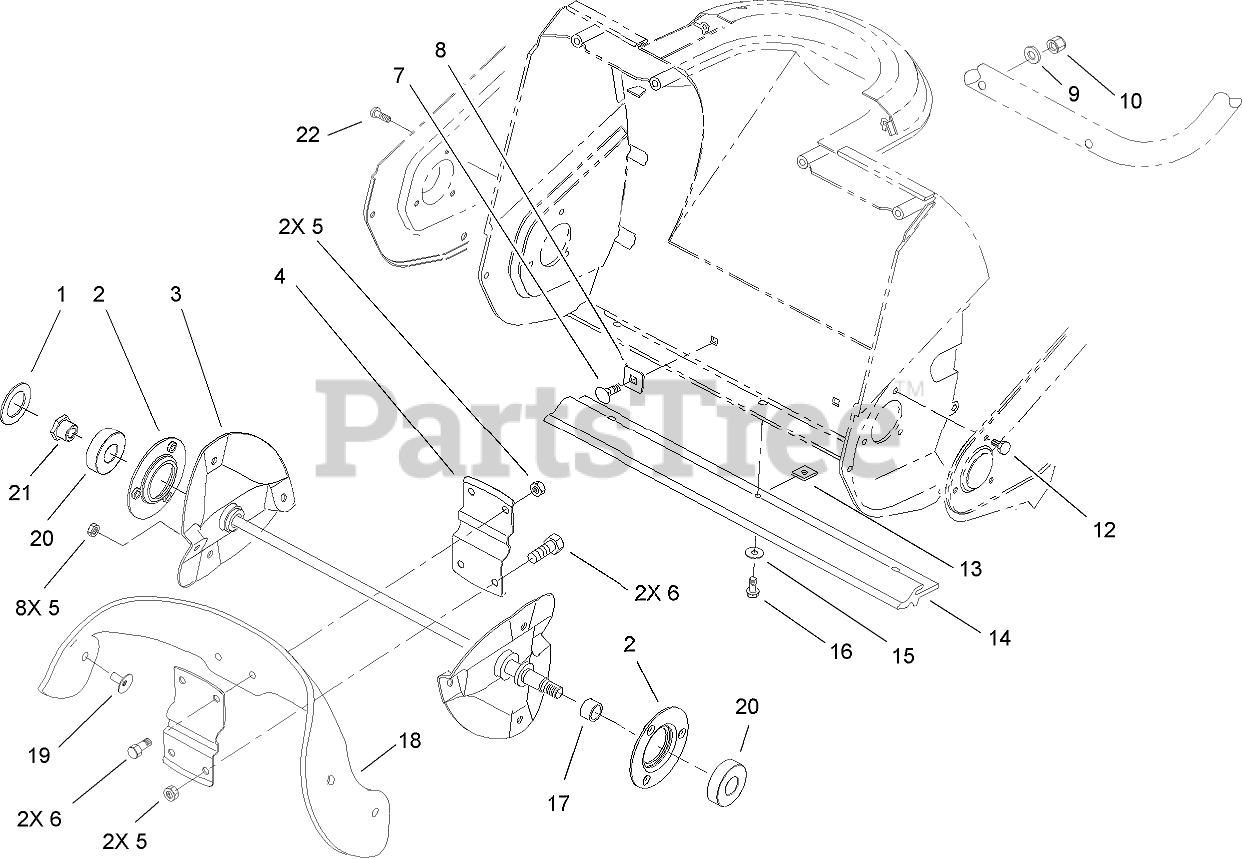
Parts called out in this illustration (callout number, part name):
1	WASHER-RUBBER
2	FLANGE-BEARING
3	ROTOR SHAFT ASM
4	SUPPORT-ROTOR
5	NUT-LOCK, NI
6	SCREW-HHF
7	SCREW-CARR
8	WASHER-SQUARE
9	WASHER
10	NUT-LOCK, NI
12	SCREW-HH, TAPTITE
13	NUT-CLIP, U
14	SCRAPER
15	WASHER-FLAT
16	SCREW-HWHTF
17	SPACER
18	BLADE-ROTOR
19	SCREW
20	BEARING-BALL
22	SCREW-HWH
